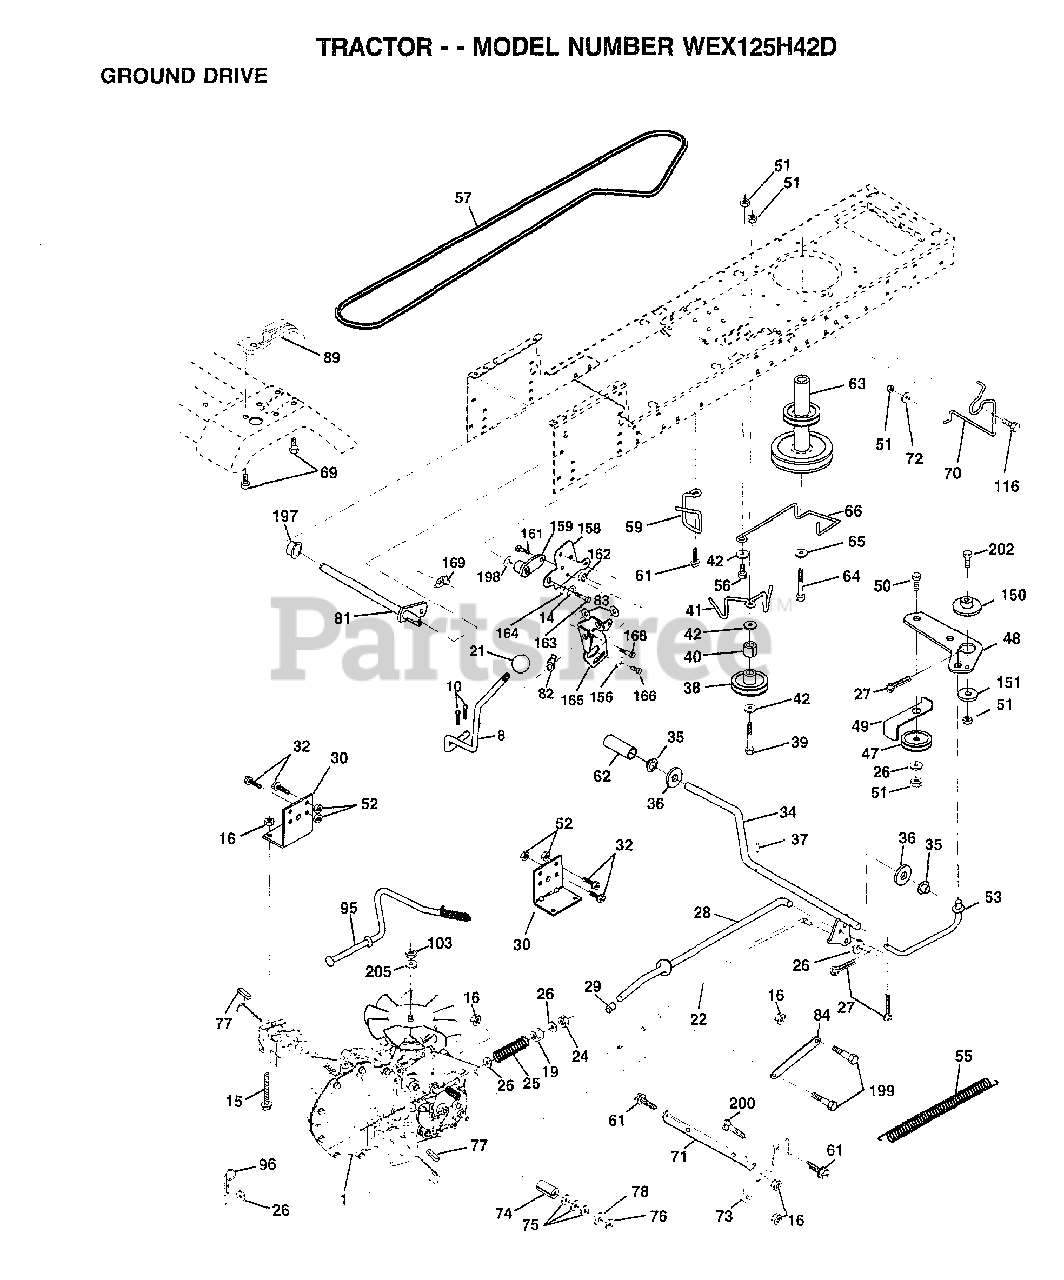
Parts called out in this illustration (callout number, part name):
8	ROD.SHIFT.FENDER.ADJ.LT.CRD
10	PIN COTTER 1/8
14	LOCKWASHER
15	BOLT.HX.FLG.5/16
16	NUT
19	NUT
21	KNOB T (1/2-HOLE)
22	ROD BRAKE HYDRO
24	NUT
25	SPRING ROD LT
26	WASHER
27	COTTER PIN
28	ROD.BRAKE.PARK.LT
29	PLUNGER CAP T
30	TRANSAXLE MTG BKT
32	BOLT
34	SHAFT ASM-PEDAL F
35	NYLON BEARING
36	WASHER LT
38	FLAT IDLER PULLEY
39	BOLT
40	SPACER T
41	"KEEPER,BELT.IDLER FLAT"
42	WASHER
48	BELLCRANK.CLUTCH
49	RETAIN BELT
53	"LINK, CLUTCH T"
55	"SPRING, RETURN LT"
57	"BELT.GD DRV 82"""
59	KEEPER BELT SPAN CTR
61	SCREW
62	PEDAL COVER T
63	PULLEY.ENGINE
64	BOLT
65	LOCKWASHER
66	KEEPER-BELT
69	SCREW HEXWSH H-L
70	KEEPER BELT ENG
71	STRAP TORQUE LH HYDRO
72	WASHER
73	STRAP TORQUE RH HYDRO
74	SPACER
75	WASHER
76	E-RING LT
77	SQUARE KEY
78	WASHER
81	SHAFT
82	"SPRING,TORSION"
83	WASHER
84	LINK TRANSAXLE
89	CONSOLE HYDRO
95	CONTROL ASSY
96	RETAINER M
116	BOLT RDHD 3/8-16
150	BUSHING.BELLCRANK.GRD.DR
151	WASHER
156	WASHER.SRRTD.5/16
158	BRKT.SHIFT.MOUNT
159	HUB.SHIFT
161	BOLT T
164	WASHER.5/8X.281X10GA
165	BRKT.PIVOT.LEVER
166	SCREW.5/16-18X5/8
168	BOLT.SHOULDER.5/16-18X.561
169	PLATE.FASTENING
197	NYLINER SNAP-IN
198	WASHER NYLINER
199	BOLT SHOULDER
200	BOLT
202	BOLT.3/8-16X1.50
